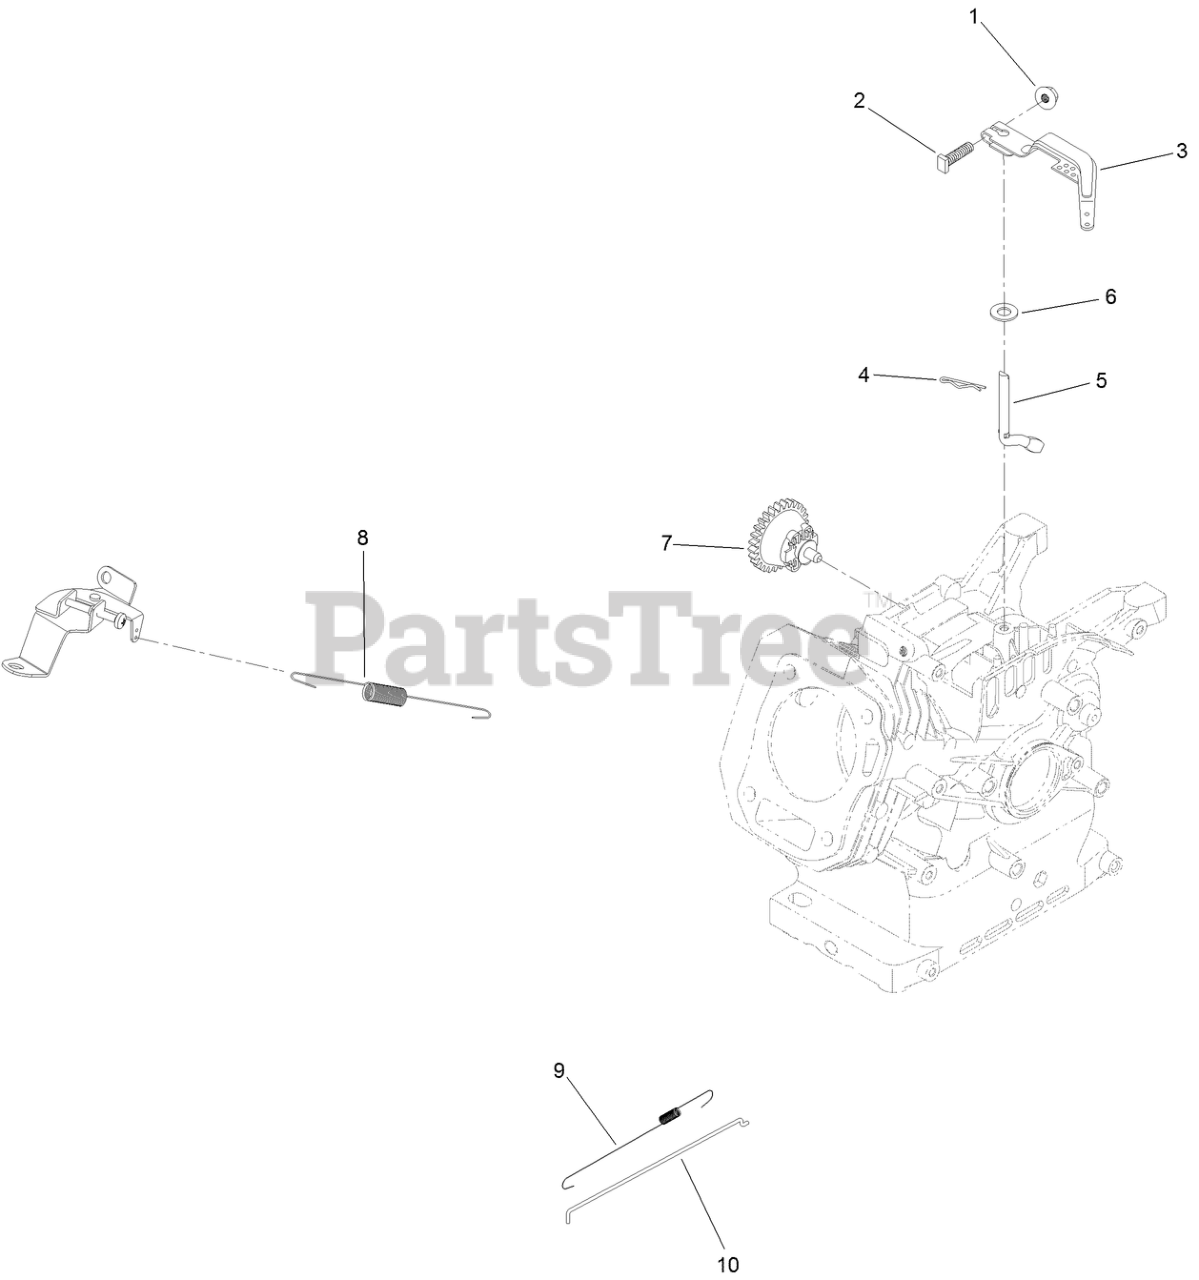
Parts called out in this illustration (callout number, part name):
1	NUT-FLANGE
2	BOLT-ARM, GOVERNOR
3	ARM-GOVERNOR
4	PIN-HAIR
5	SHAFT-GOVERNOR
6	WASHER-PLAIN
7	GOVERNOR GEAR ASM
8	SPRING-GOVERNOR
9	SPRING-RETURN, THROTTLE
10	ROD-GOVERNOR
